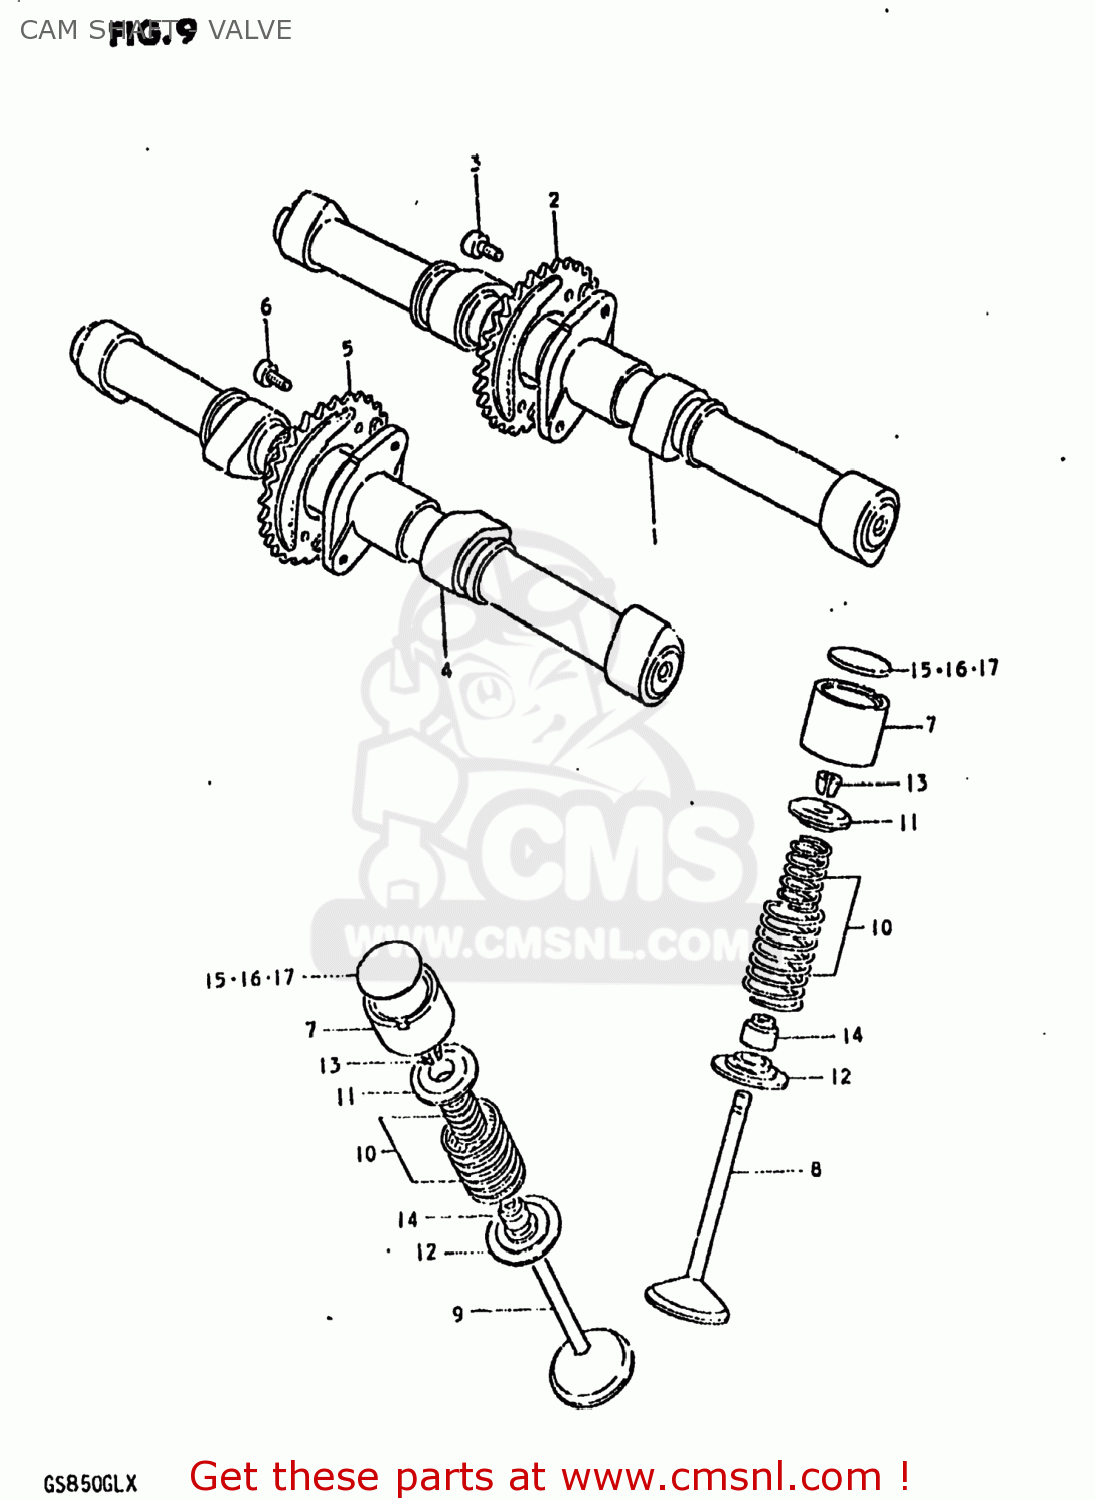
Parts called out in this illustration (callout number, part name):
1	CAMSHAFT
2	SPROCKET,CAMSHAFT
3	BOLT 6X11
4	CAMSHAFT,EXHAUST
5	SPROCKET,EXHAUST CAMSHAFT
6	BOLT 6X11
7	TAPPET
8	VALVE,INTAKE
9	VALVE,EXHAUST
10	SPRING SET,VALVE
11	RETAINER,VALVE SPRING
12	SEAT,VALVE SPRING
13	COTTER VALVE
14	SEAL,OIL(7X14.4X9)
15	SHIM,TAPPET
16	SHIM,TAPPET
17	SHIM,TAPPET
18	SHIM SET,TAPPET
19	CASE
